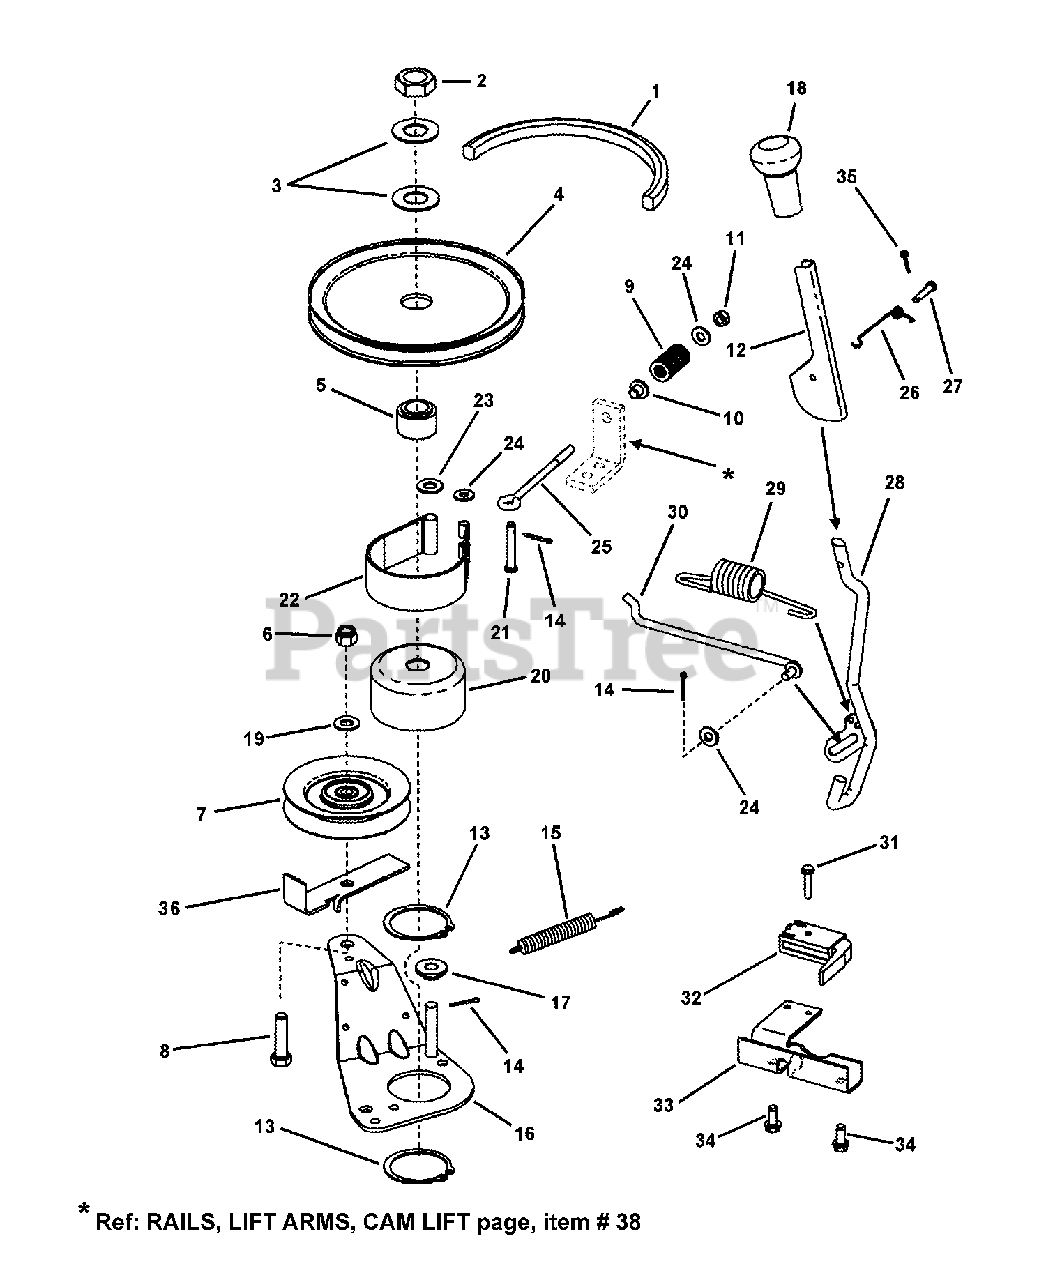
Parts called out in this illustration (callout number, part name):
1	* BELT, Drive (72.75" AA Section)
2	NUT, 3/4-16 Hex Jam, GR 8
3	WASHER, 49/64" I.D. x 1-1/2" O.D. Flat
4	PULLEY, Deck
5	PULLEY, Hub (Powdered Metal)
6	NUT, 3/8-16 Hex Nyloc
7	IDLER PULLEY, 4" Idler
8	SCREW, 3/8-16 x 1-1/2" Hex Head Cap, GR 5
9	SPRING, Rectangular Wire Die, Blue
10	BUSHING, Flange .27 x .35 x .4
11	NUT, 1/4-20 Hex Top Lock
12	HANDLE, Blade Engagement (Flip)
13	RING, 2" External Retaining
14	PIN, 3/32 x 3/4" Cotter
15	SPRING, Extension, 4" x 1/2" Diameter
16	WELDMENT, Idler Arm
17	SPACER, .39 x 1.0 x .31 Nylon
18	GRIP, Handle
19	WASHER, 3/8" Flat
20	DRUM, Brake Spindle
21	PIN, 1/4 x 1-5/8" Clevis
22	BAND, Brake (Formed)
23	WASHER, 3/8" Flat
24	WASHER, 1/4" Flat
25	EYE-BOLT, 1/4-20 x 4"
26	SPRING, Torsion, Flip Handle
27	PIN, 3/16 x 1" Clevis
28	WELDMENT, Blade Engagement Handle
29	SPRING, Blade Handle
30	ROD, Idler Control
31	SCREW, #10-32 x 1" Hex Washer Head Self-Tap
32	SWITCH, Deck Interlock (NO)
33	MOUNT, Handle/Switch
34	SCREW, 1/4-20 x 5/8" Hex Washer Head Self-Tap
35	PIN, 3/32 x 1/2" Cotter
36	RESTRICTOR, Belt
